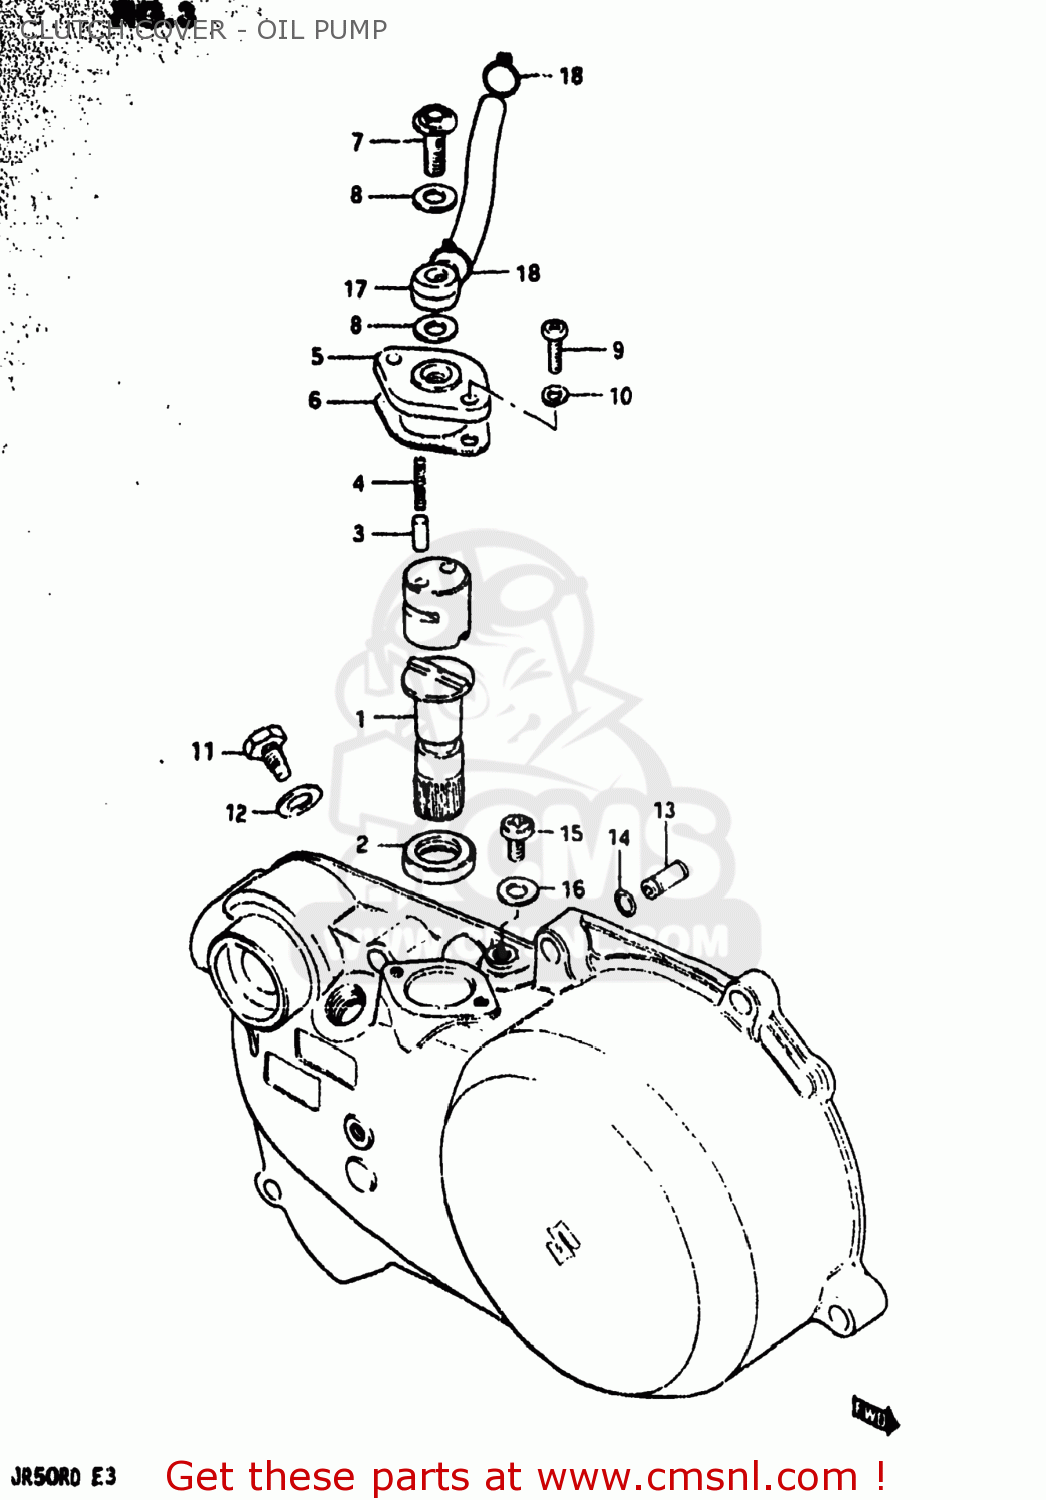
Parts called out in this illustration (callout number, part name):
1	GEAR,OIL PUMP DRIVE
2	SEAL,OIL(12X18.5X3)
3	PIN(2.3X7.5)
4	SPRING
5	CAM,OIL PUMP
6	GASKET,OIL PUMP (MCA)
7	UNION BOLT
8	GASKET(6.2X11X1).2 (NAS)
9	SCREW
10	LOCK WASHER
11	BOLT(6X10)
12	WASHER
13	VALVE,CRANK CHECK
14	O RING(D:1.05,ID:3.1)
15	SCREW
16	GASKET(5X9.5X1) (NAS)
17	HOSE,OIL NO.1
18	CLIP
